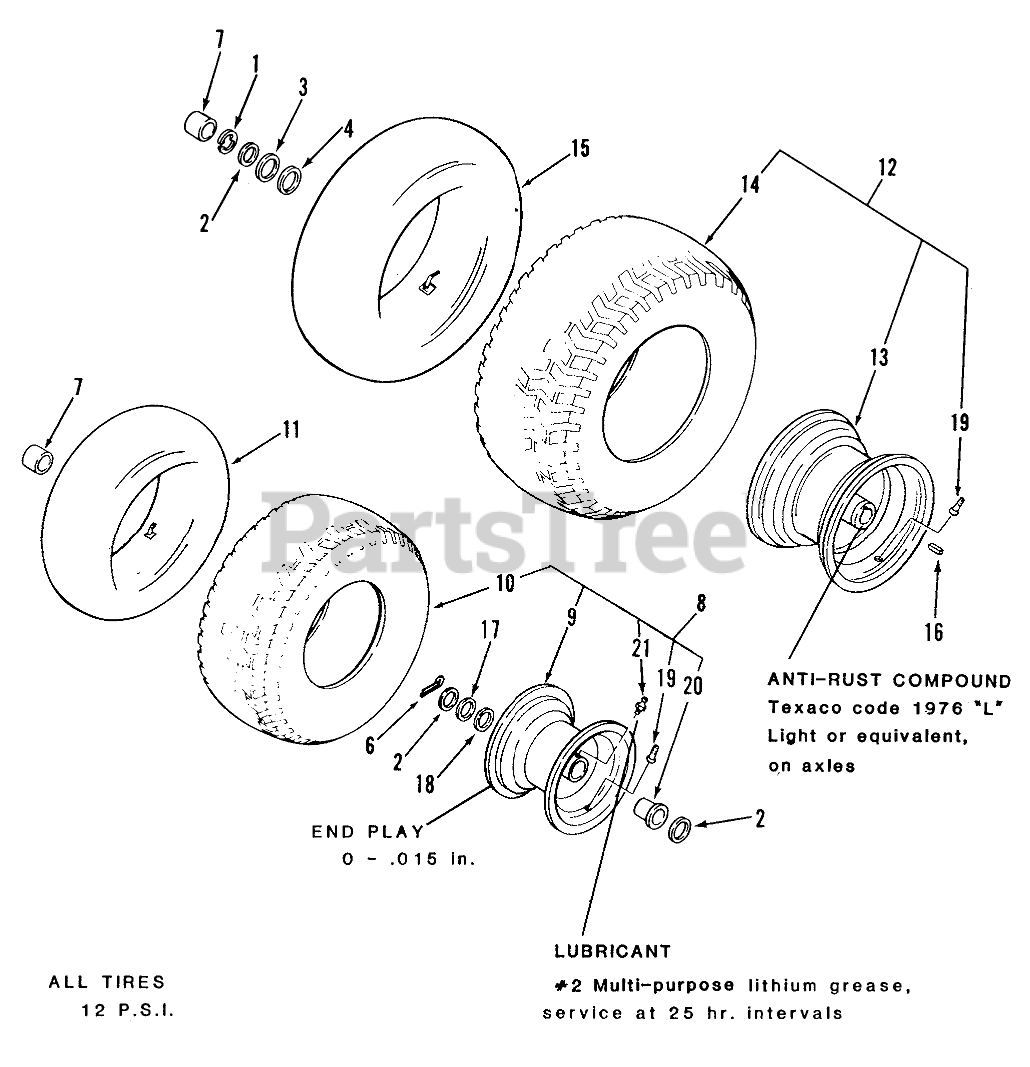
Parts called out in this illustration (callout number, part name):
1	E Ring
2	WASHER-FLAT
3	WASHER-SHIM
4	WASHER
6	COTTER PIN-4
7	HUB CAP
8	Front Wheel and Tire 13 x 5.00-6 (includes items 5, 6, 8, 9 & 10) 208-4SB, 211-5SB & 211-4.
9	ASS'Y-WHEEL
10	TIRE
11	Front Tube-Service Only
12	Assy-Wheel & Tire-Rear 211-3 Only
13	WHEEL
14	TIRE 18 X 8.50 X 8
15	Rear Tube-Service Only
16	SQ KEY
17	WASHER
18	WASHER-SHIM
19	VALVE
20	FLANGE BEARING
21	Zerk
